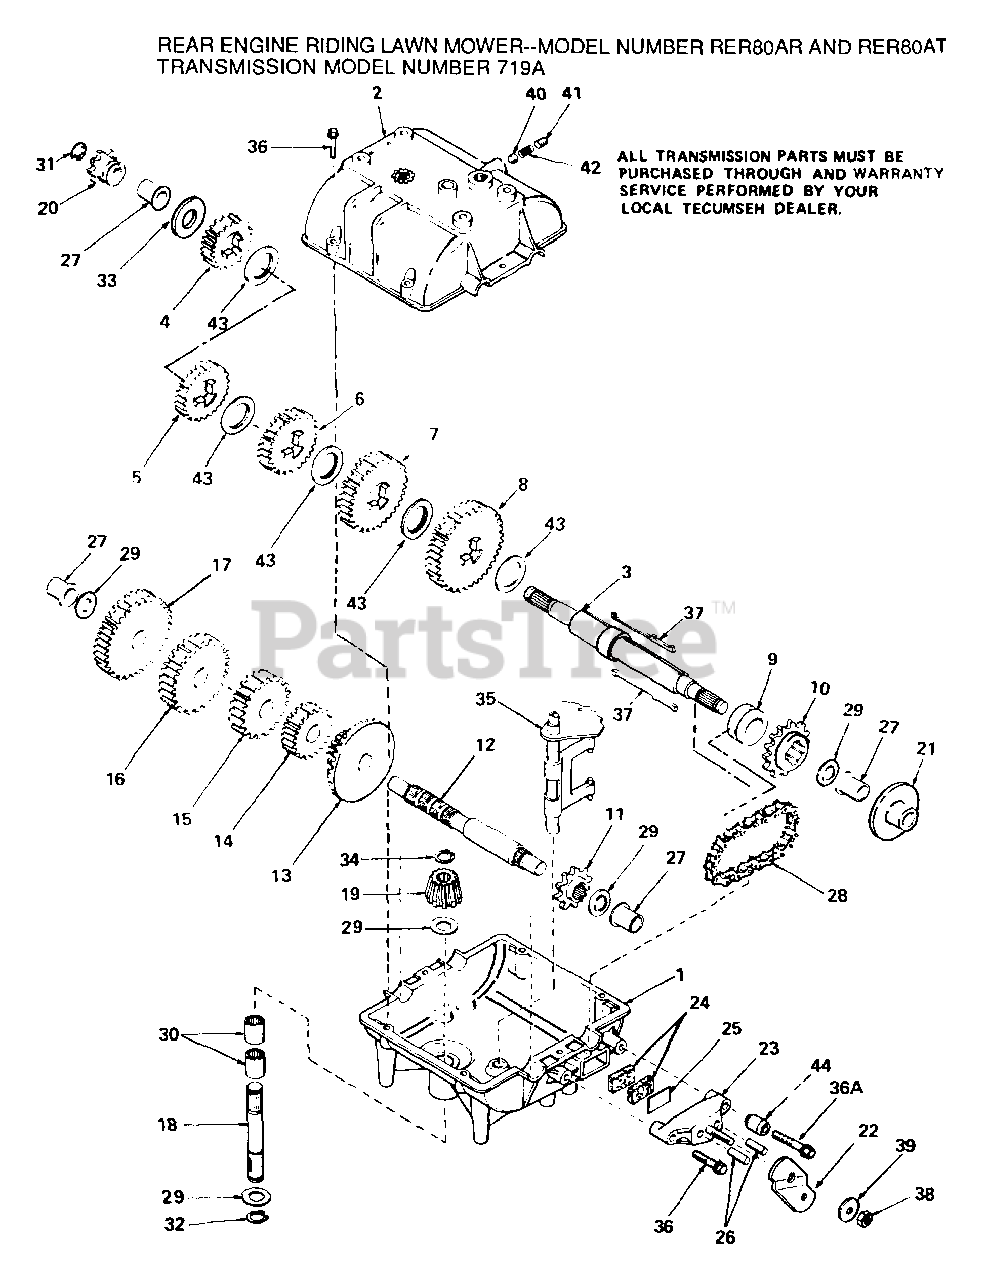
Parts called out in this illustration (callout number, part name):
1	No Desciption for Part
2	COVER, TRANSMISSION
3	No Desciption for Part
5	No Desciption for Part
6	No Desciption for Part
7	No Desciption for Part
8	GEAR, SPUR, 35 TEETH
9	COLLAR, SHIFT
10	No Desciption for Part
11	No Desciption for Part
12	No Desciption for Part
13	No Desciption for Part
14	No Desciption for Part
15	No Desciption for Part
16	No Desciption for Part
17	No Desciption for Part
18	SHAFT, INPUT
19	No Desciption for Part
20	No Desciption for Part
21	DISK, BRAKE
22	LEVER, BRAKE
23	No Desciption for Part
25	PLATE BRAKE PAD
27	No Desciption for Part
28	No Desciption for Part
29	WASHER THRUST
30	No Desciption for Part
31	No Desciption for Part
32	RING, RETAINER
33	WASHER, THRUST
34	RETAINING RING
35	No Desciption for Part
36	SCREW, 1/4-20 X 1-1/4
36A	SCREW FLNG HEX 1/4-20 X 2-1/4
37	KEY (4 REQUIRED)
38	LOCKNUT 5/16-24
39	WASHER, FLAT
40	BALL STEEL, 5/16" DIA.
41	SCREW, 3/8-16 X 3/8"
43	WASHER THRUST
